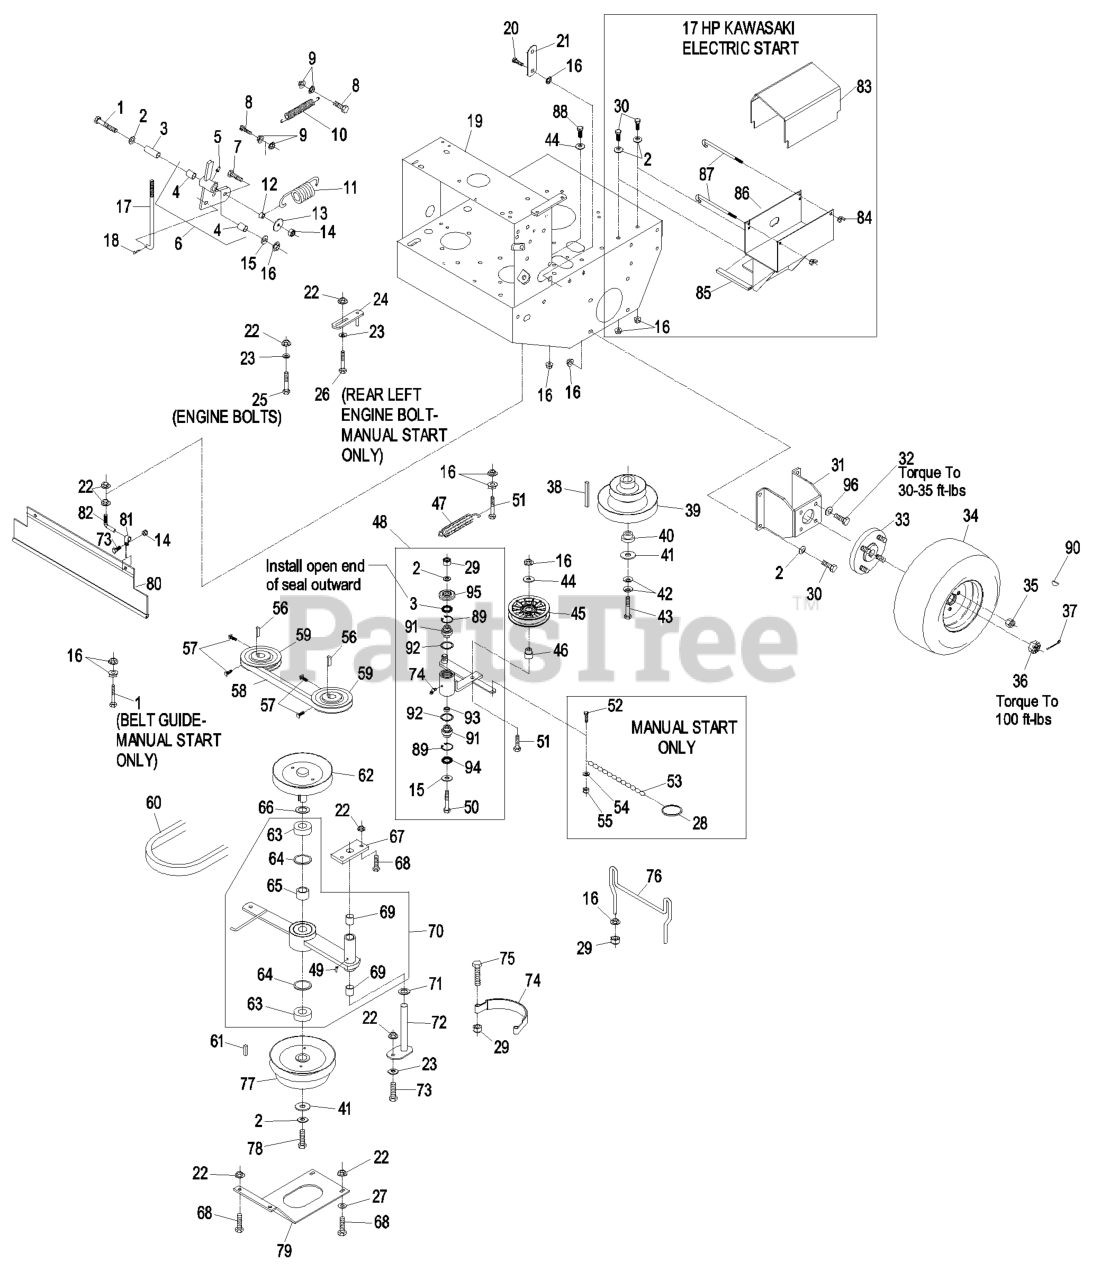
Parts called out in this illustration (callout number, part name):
1	SCREW-HH
2	WASHER-BELLEVILLE
3	SEAL-LIP, SINGLE
4	SLEEVE-BEARING
5	FITTING-GREASE
6	ASM,PIVOT W/BUSHINGS
7	SCREW-HH
8	SCREW-HH
10	SPRING,EXTENSION
11	SPRING,EXTENSION
12	SPACER,CLUTCH ANCHOR
14	NUT-LOCK, NI
15	WASHER-FLAT
16	NUT-HHF, WHIZ
17	LINKAGE,LOWER
18	PIN-COTTER
19	KIT,TTHP ENG DECK
20	SCREW-HH
21	ARM-LIFT, DECK
23	WASHER-SPRING
24	GUIDE-BELT
25	SCREW-HH
26	SCREW-HH
27	WASHER-FLAT
28	RING-SPLIT
29	NUT-LOCK, NI
30	SCREW-HH
31	WLD,MOTOR MOUNT 36
32	SCREW-HH
34	WHEEL AND TIRE ASM
35	NUT-LUG
36	NUT-HEX, SLOTTED
37	PIN-COTTER
38	KEY,MACH 1/4X1/4X2-5/8
39	SHEAVE, DRIVE
40	BUSHING,CLUTCH KEEPER
42	WASHER-SPRING
43	SCREW-HH
44	WASHER-FLAT
45	PULLEY-IDLER, FLAT
46	BUSHING-IDLER
48	KIT,PUMP IDLER ARM TTHP
49	FITTING-GREASE
50	SCREW-HH
51	SCREW-HH
52	SCREW-HSH
53	CHAIN-LINK, TWIST
54	WASHER-FLAT
55	NUT-LOCK, NI
57	SCREW-SET
58	BELT,COG A 50.55
59	SHEAVE ASM
60	BELT,B-38.0
62	SHEAVE, W/ SHAFT
63	BEARING,CLUTCH SHAFT
64	RING-SNAP
65	SPACER,CLUTCH BEARING
66	WASHER-SPACER
67	PLATE-CLUTCH PIVOT
68	SCREW-HH
69	SLEEVE,BEARING
70	ASM,CLUTCH ARM W/BEARING
71	WASHER-SPACER
72	WLD,PIN PIVOT
73	SCREW-HH
74	BAND,BRAKE BLADE
75	SCREW-HH
76	GUIDE,BELT (PLTD)
77	SHEAVE,6.13 W/HUB
78	SCRW,CAP HH
79	PLATE-GUARD
80	SHIELD-DRAG
81	CLIP-LOOM
82	MOUNT,DRAG SHIELD
83	COVER,BATTERY W/DECAL
84	WINGNUT
85	TRIM-LOK
86	ASM,BATTERY STAND W/TRIM
87	BOLT - HOLD DOWN
88	SCREW-HH
89	RING-SNAP
90	KEY-WOODRUFF
91	BEARING-SPHERICAL
94	SEAL-LIP, DOUBLE
95	GUARD-TOP
96	Washer, Spring Disc
